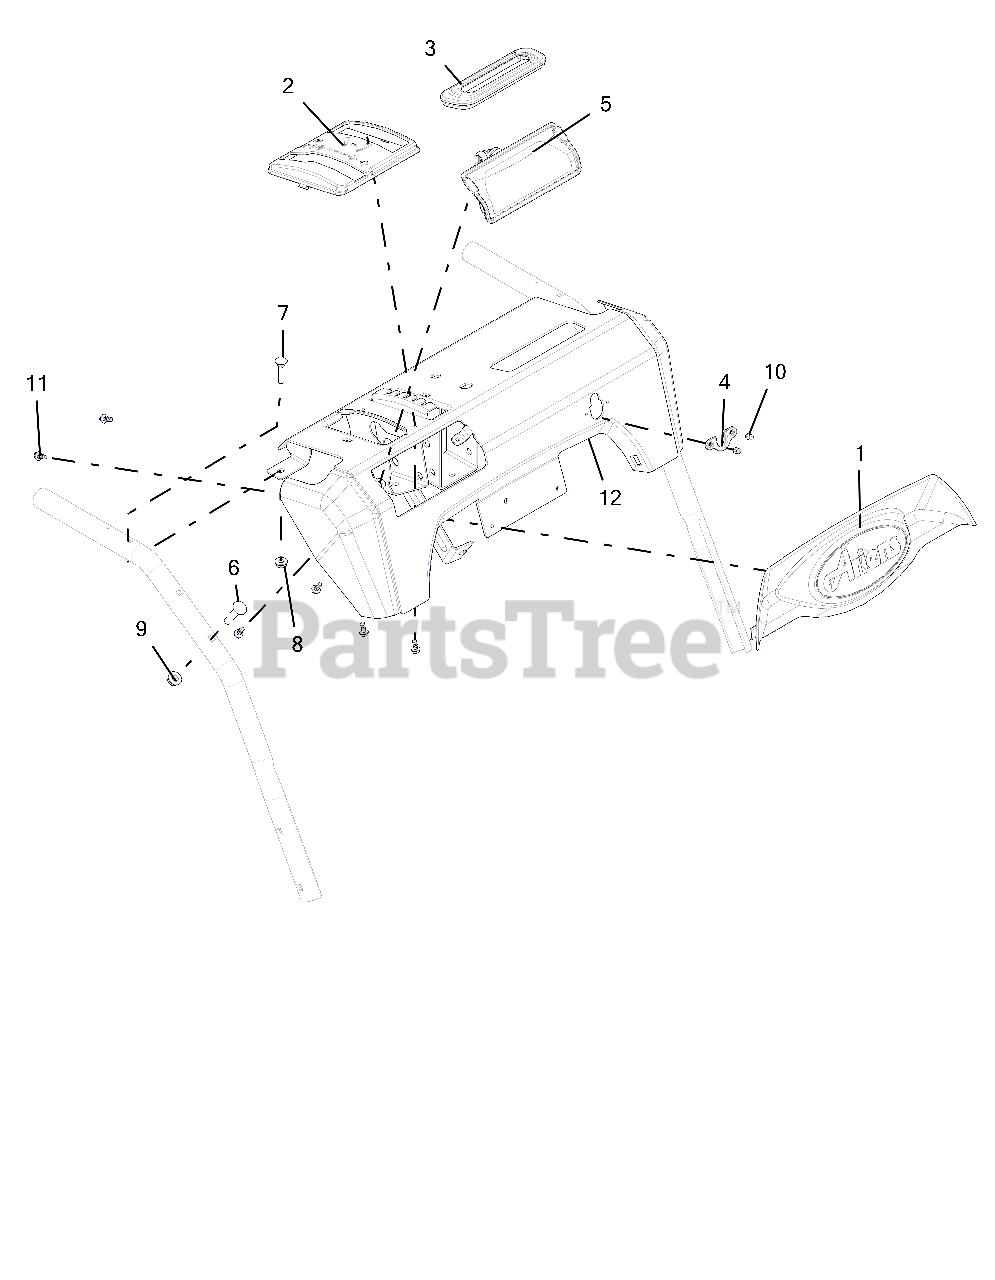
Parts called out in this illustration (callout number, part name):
1	DASH BEZEL, ARIENS LOGO - PRO
2	SHIFT BEZEL W/ NEUTRAL
3	GROMMET, BOOT, QUICK TURN
4	GROMMET, CABLE, QUICK TURN 2
5	HEADLIGHT ASY, HALO 20W 2SHOT
6	@BLT-RDHDSQNK .31-18X1.50 G5YZ
7	BLT-RDHDXLSQNK.25-20X1.25 G5ZC
8	@NUT-LK-CTR-FLG .25-20 YWZC
9	@NUT-LK-TOP-FLG .31-18 YWZC
10	RVT-POP #43 .125X.313 STL ZINC
11	SCR-TAP #10X.50 BOSS INDHXHD
12	KIT,DASH PANEL W/DECAL,HYD 12V
